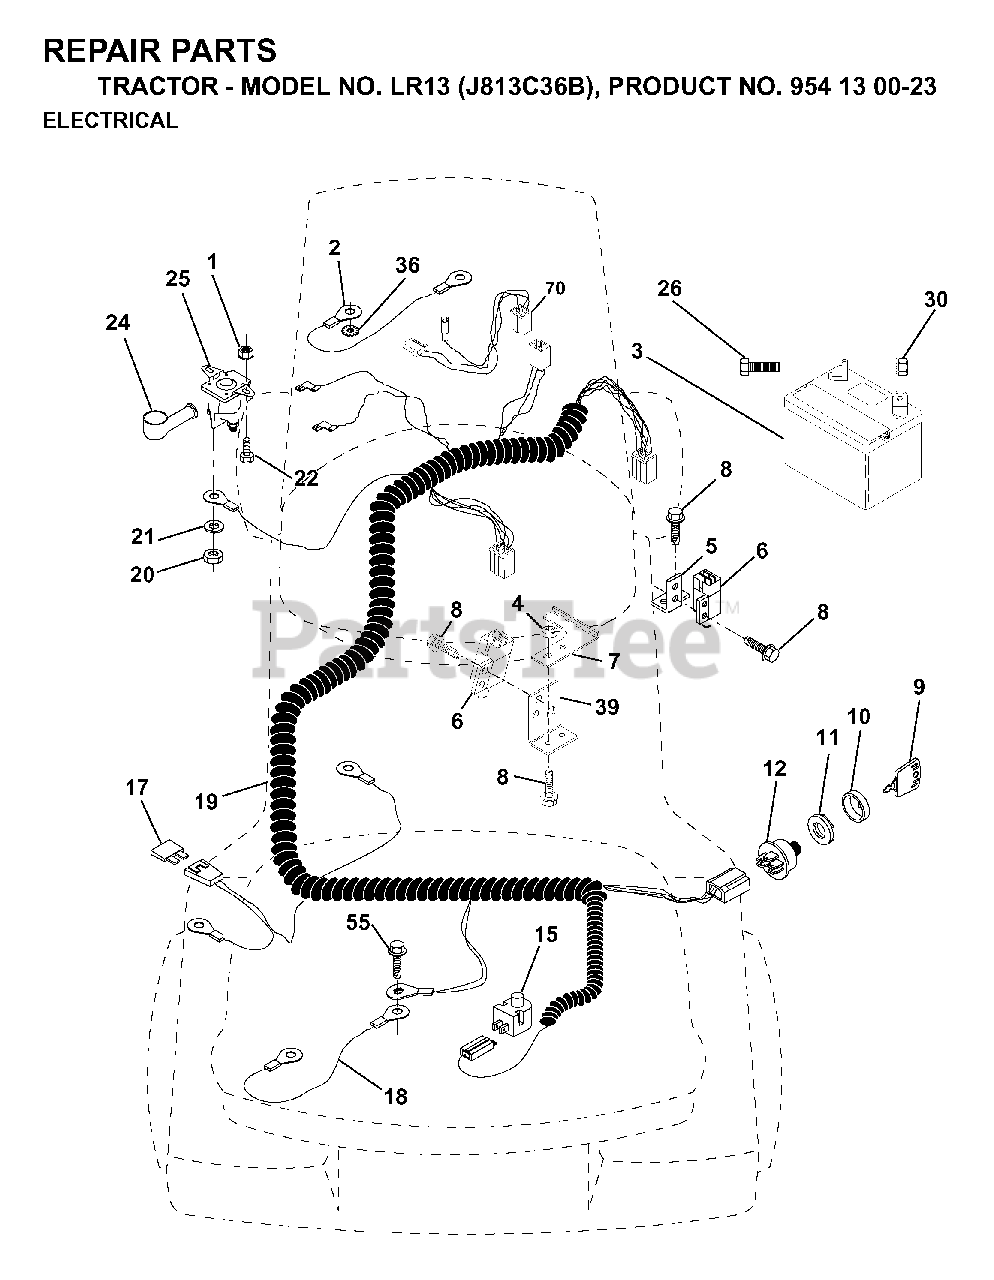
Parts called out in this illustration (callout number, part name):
2	CABLE ASM
5	BRACKET LT
6	SWITCH INTERLOCKT
7	KEEPER, ACTUAT. L.R.
9	KEY MLD GEN DELTA
10	COVER SWITCH KEY
11	NUT, IGNITION
12	IGNITION SWITCH
15	SWITCH SEAT
19	HARNESS IGN LR NLA
20	NUT
21	LOCKWASHER
24	TERMINAL COVER
25	SOLINOID
30	NUT
31	LIGHTBULB
32	HARNESS LIGHT SOCKET
33	SWITCH LT
36	LOCKWASHER
55	SCREW LT
70	HARNESS, ENGINE
